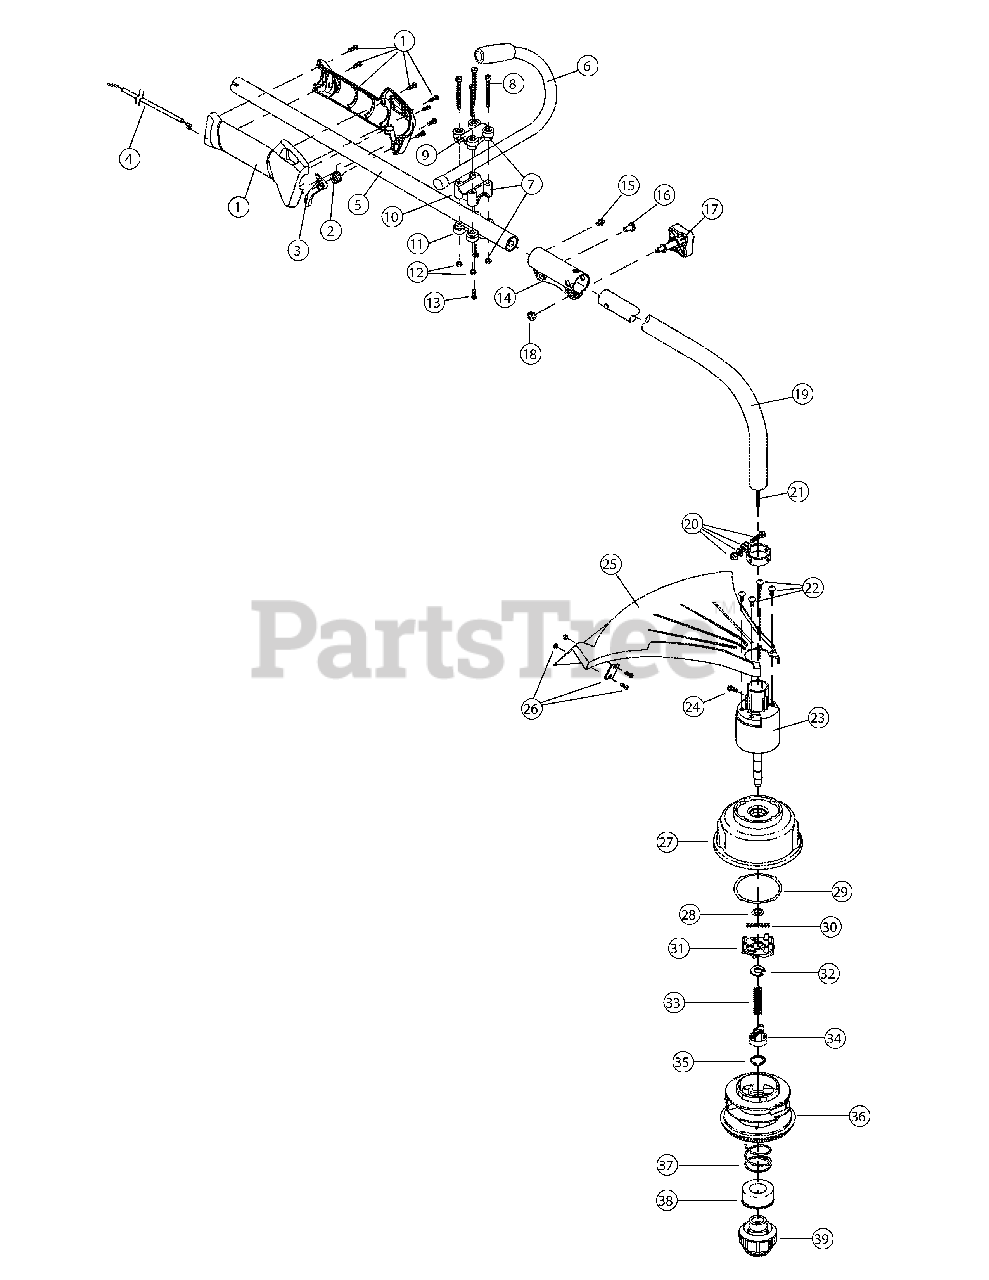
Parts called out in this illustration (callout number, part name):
1	Throttle Housing Assembly
2	Throttle Trigger Spring
3	Throttle Trigger
4	Throttle Cable
5	Upper Drive Shaft Housing
6	J-Handle Assembly
7	Handle Bracket Assembly
9	Upper Handle Clamp
10	Middle Handle Clamp
11	Lower Handle Clamp
13	Anti-Rotation Screw
14	Split Boom Coupler
17	Adjustment Knob
18	Knob Retaining Nut
19	Lower Drive Shaft Housing
20	Lower Clamp Assembly
21	Lower Flexible Drive Shaft
22	Shield Mounting Screw
23	Bushing Housing Assembly
24	Anti-Rotation Screw
25	Shield Assembly
26	Blade Assembly
27	Outer Spool Assembly
28	Retainer
29	Thrust Washer
30	Small Spring
31	Slider
34	Plunger
36	Inner Reel
37	Large Spring
38	Foam Seal
39	Bump Head Knob Assembly
